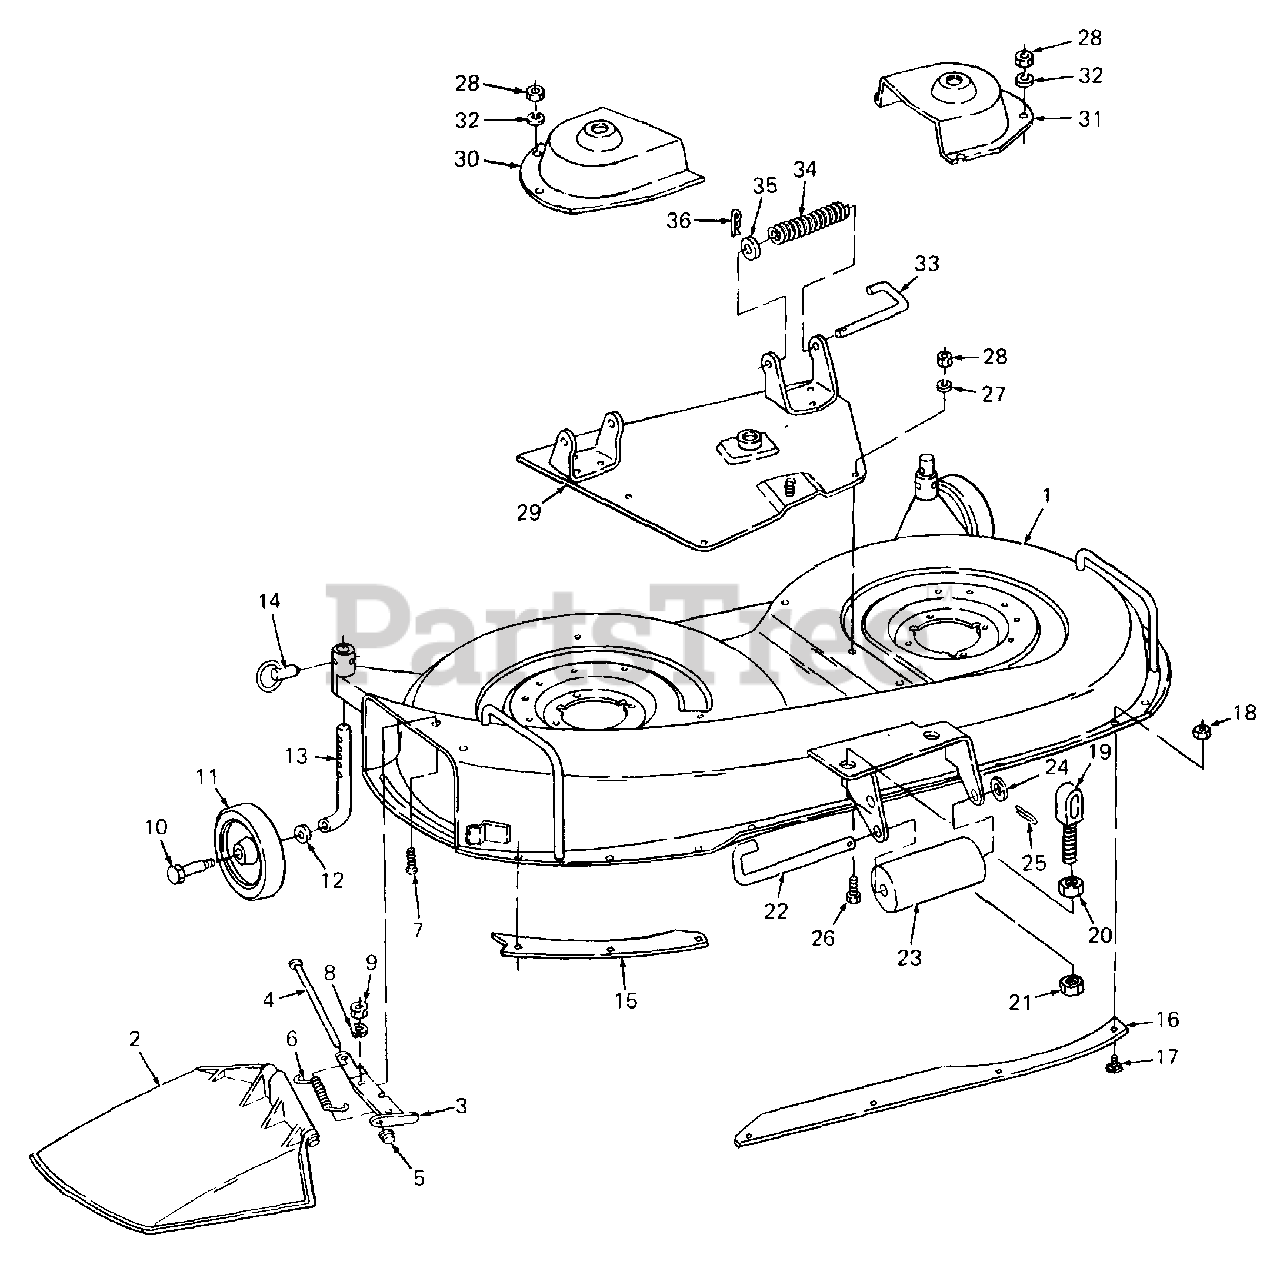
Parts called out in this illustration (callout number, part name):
2	Deflector Assy, Chute
3	Bracket, Hinge Mtg
4	Pin, Hinge, .25 Dia X 6.75 Lg
5	Cap, Speed Nut
6	Spring, Torsion
7	Screw, Truss Machine, 1/4-20 X .75 Lg, Phillips
8	Washer, Lock, 1/4 Dia
9	Nut, Hex, 1/4-20
10	Screw, Shoulder
11	Wheel, Gauge, 5 in. Dia
12	Washer, Bell, .380 X .88 X .062 Thk
13	Axle, Deck
14	Pin, Clevis w/Detent Ball
16	Skirt, Extension
17	Bolt, Carriage, 1/4-20 X .50 Lg
18	Nut, Hex Sems, 1/4-20
19	Hanger, Front Mower Support
20	Nut, Hex Jam, 5/8-11 GR5
21	Nut, Hex Jam Lock, 5/8-11 GR5
22	Pin, Roller, 1/2 Dia X 7.31 Lg
24	Washer, Flat, .510 X 1.0 X .060 Thk
25	Pin, Cotter, 1/8 Dia X 1.0 Lg
26	Screw, Hex Cap, 5/16-18 X .75 Lg GR5
27	Washer, Lock, 5/16
28	Nut, Hex, 5/16-18 GR5
33	Pin, Mower Support
34	Spring, Compression
35	Washer, Flat, .531 X .930 X .050 Thk
36	Pin, Spirol Spring, 3/16 Dia X .75 Lg
